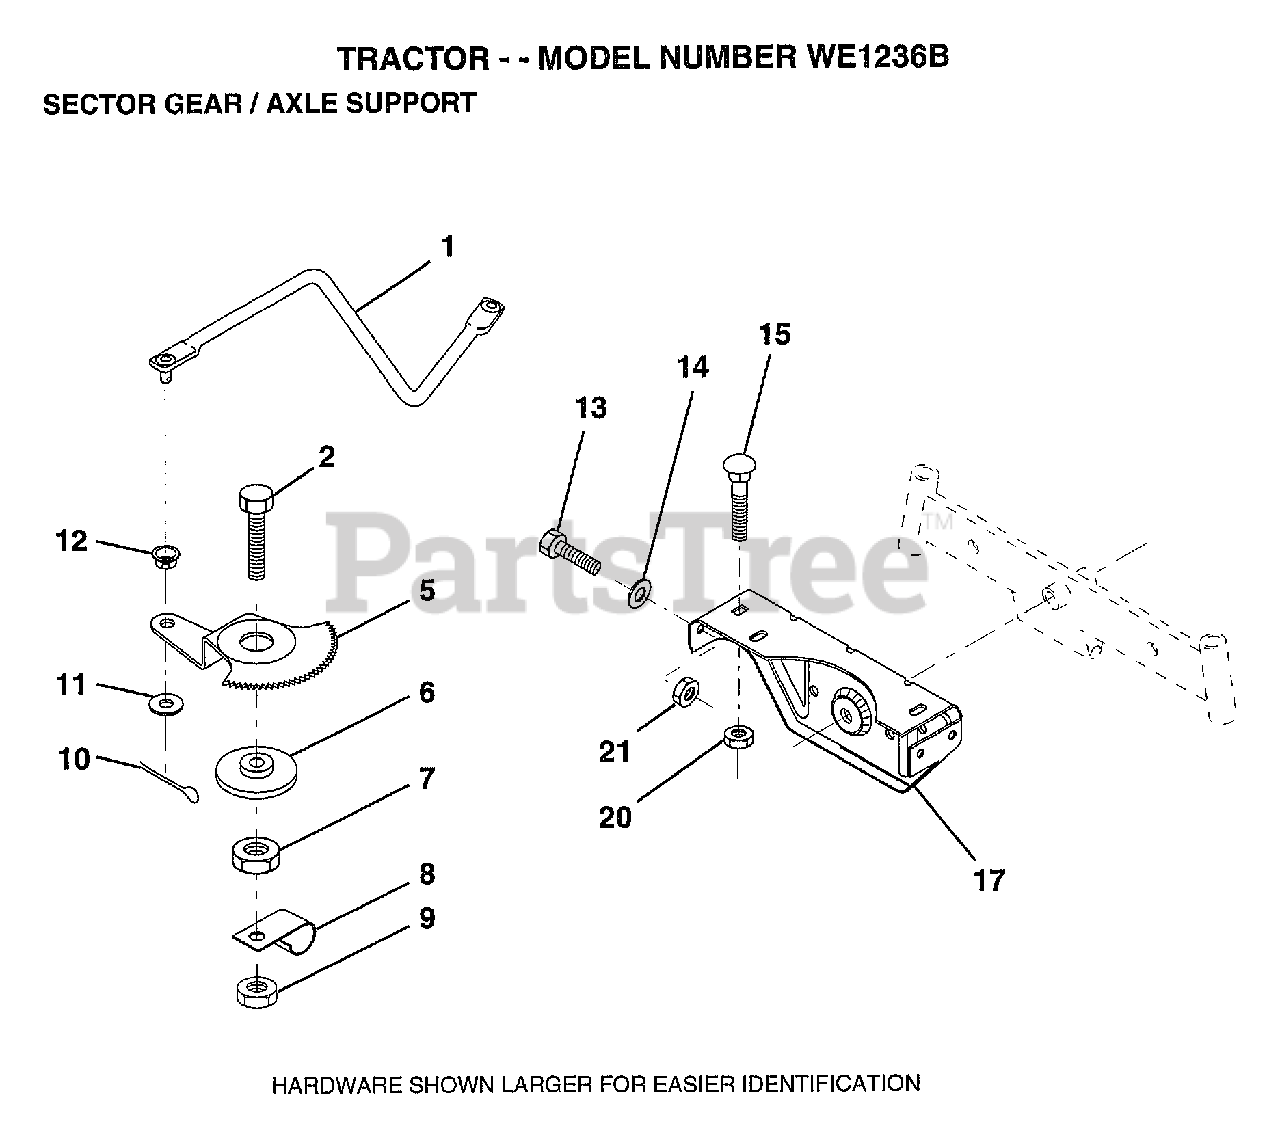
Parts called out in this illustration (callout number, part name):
1	DRAG LINK
2	"BOLT,HEX"
5	GEAR SECTOR
6	BUSHING
7	NUT
8	CLIP INSULATOR
9	NUT LTV
10	COTTER PIN
11	WASHER
12	BUSHING.DRAGLINK
13	BOLT
14	WASHER
15	BOLT
17	SUPT AXLE FRONT
